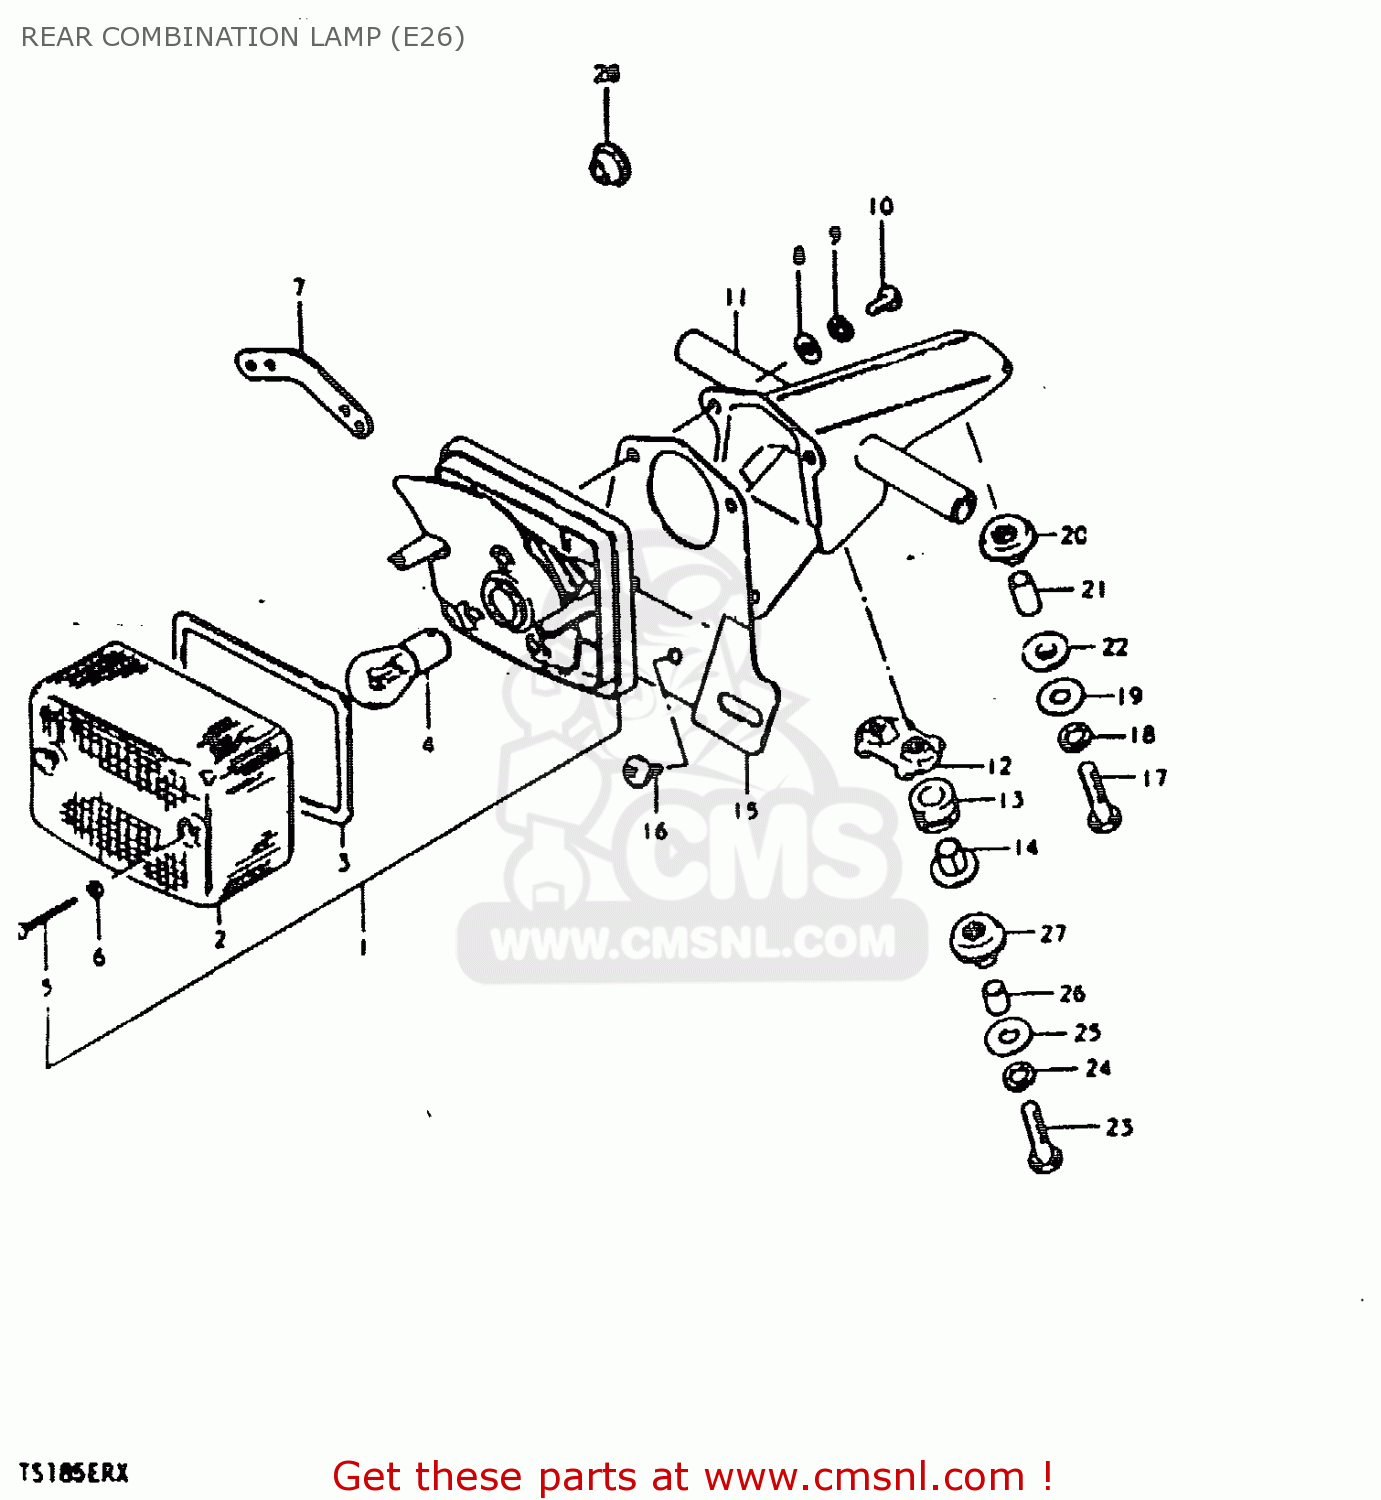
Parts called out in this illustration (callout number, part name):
1	LAMP UNIT, TAIL
2	LENS
3	GASKET (NAS)
4	BULB (6V,21/5W)
5	BOLT
6	GASKET (NAS)
7	PLATE,REAR COMBINATION LAMP
8	WASHER
9	WASHER
10	SCREW
11	BRACKET ASSY
12	PLATE
13	CUSHION
14	SPACER
15	PLATE, LICENSE
16	SCREW
17	BOLT
18	LOCK WASHER
19	WASHER (6.5X20X1.2)
20	CUSHION
21	SPACER
22	CUSHION
23	BOLT 6X40
24	LOCK WASHER
25	WASHER (6.5X20X1.2)
26	SPACER (6.8X10X11.5)
27	CUSHION
28	GROMMET
